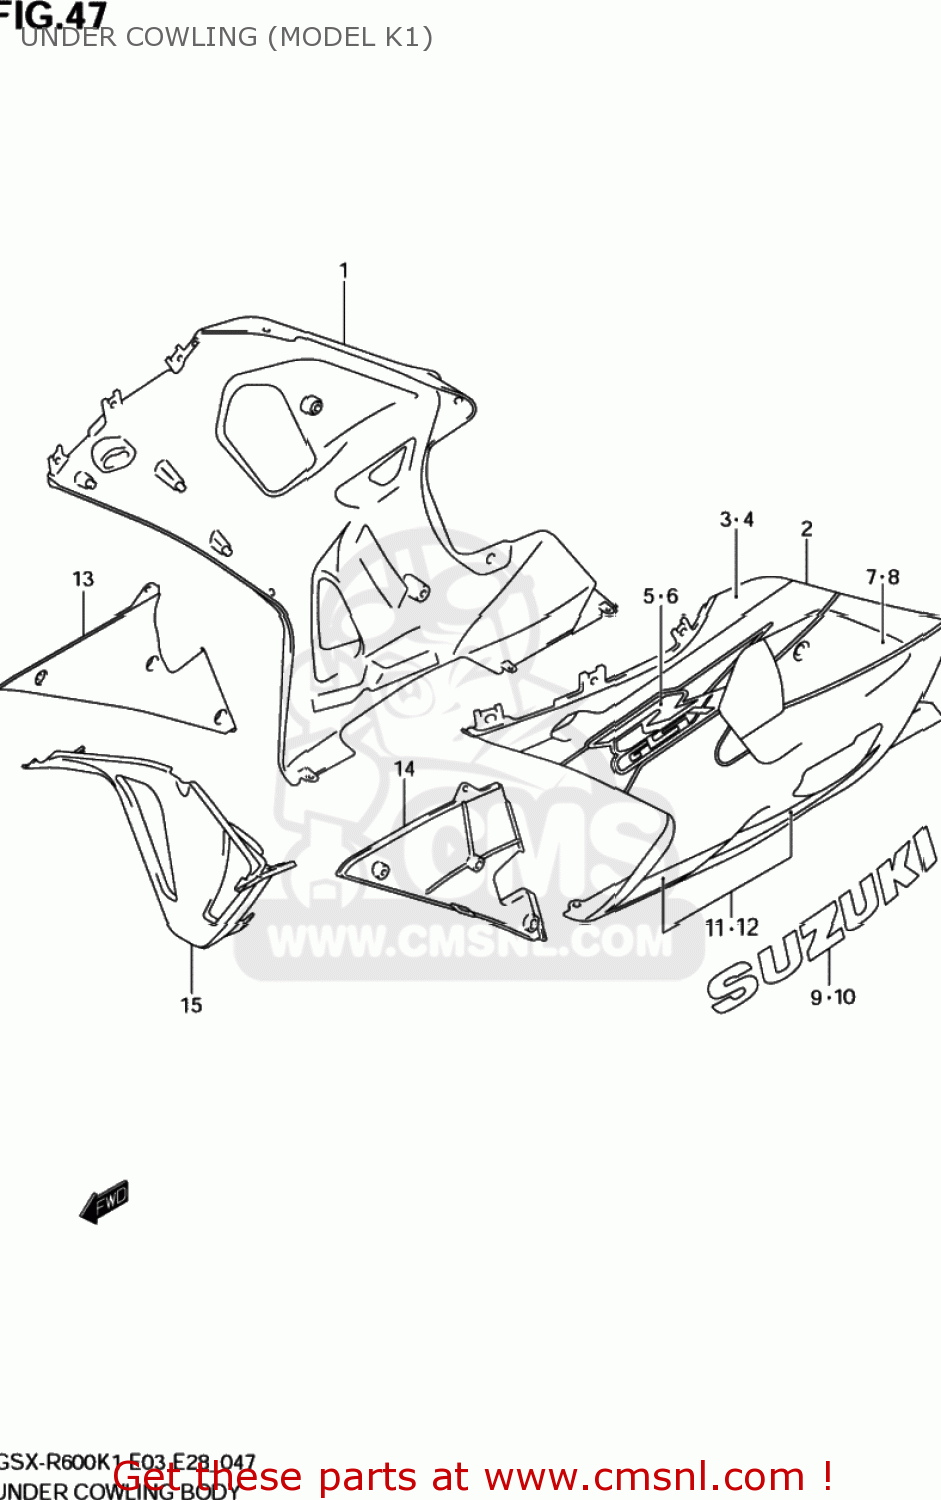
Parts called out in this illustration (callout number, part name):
1	COWLING ASSY,UNDER,R
2	COWLING ASSY,UNDER,L
3	TAPE,UNDER UPR,R
4	TAPE,UNDER UPR,L
5	TAPE(GSXR),UNDER,R
6	TAPE(GSXR),UNDER,L
7	TAPE SET,UNDER CTR,R
8	TAPE SET,UNDER CTR,L
9	EMBLEM SET,SUZUK,R
10	EMBLEM SET,SUZUK,L
11	TAPE SET,UNDER LWR,R
12	TAPE SET,UNDER LWR,L
13	COWLING,UNDER INNER,R
14	COWLING,UNDER INNER,L
15	COWLING,UNDER CTR
